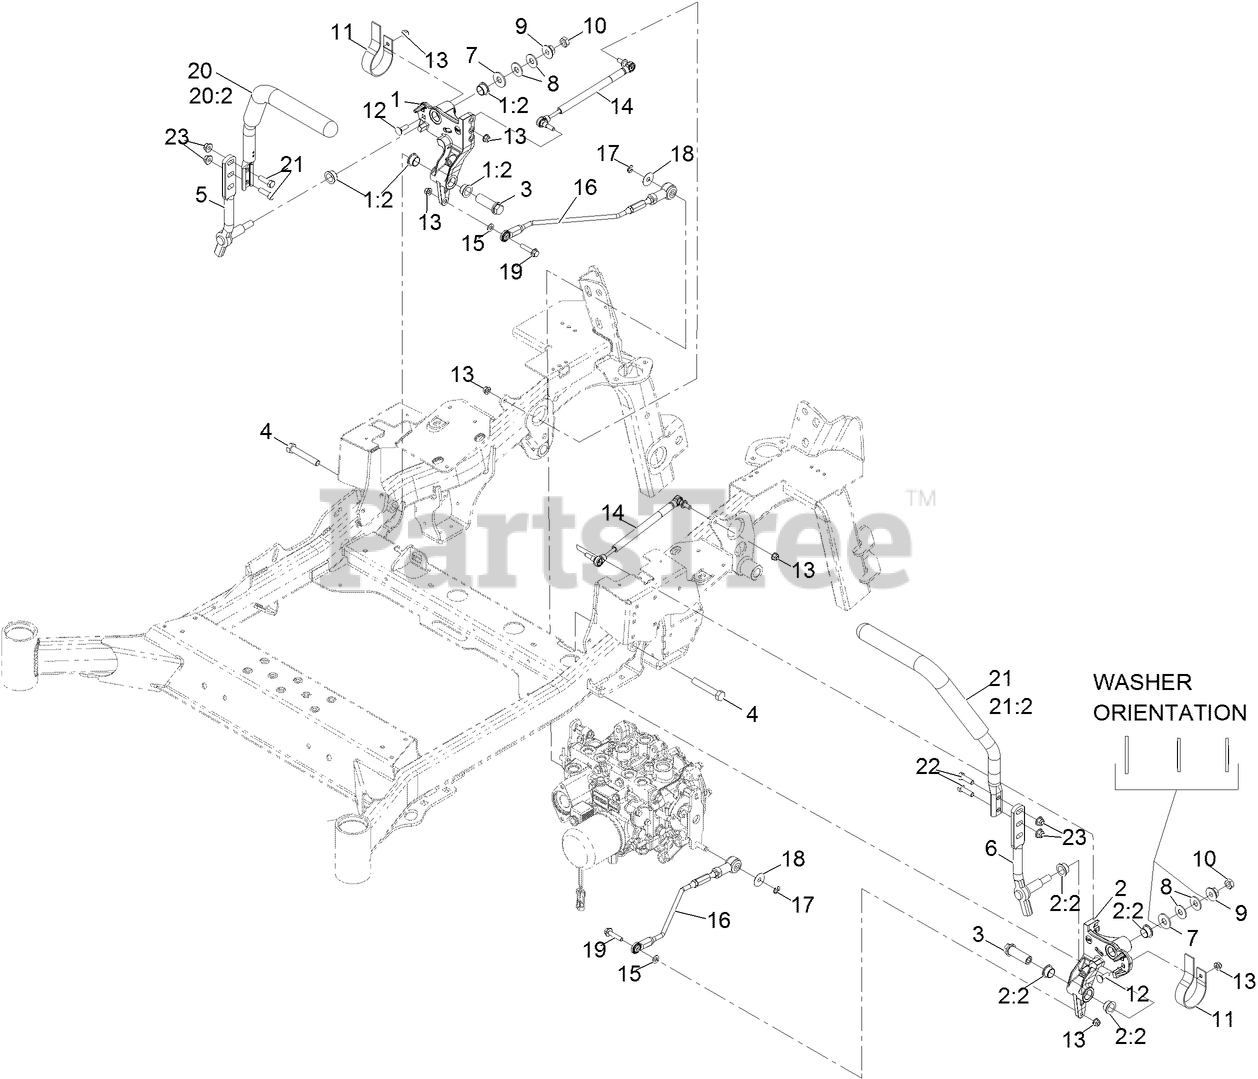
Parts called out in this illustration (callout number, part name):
1	RH MOTION CONTROL AND BUSHING ASM
1:2	BUSHING-FLANGE
2	LH MOTION CONTROL AND BUSHING ASM
2:2	BUSHING-FLANGE
3	HUB-THREADED
4	SCREW-HH
5	LEVER-CONTROL MOTION, RH
6	LEVER-CONTROL MOTION, LH
7	WASHER-FLAT
8	WASHER-SPRING
9	NUT-HF
10	NUT-JAM
11	SPRING-LEAF
12	BOLT-CARR
13	NUT-HF, NI
14	DAMPER-CONTROL, MOTION
15	WASHER-PLAIN
16	FRONT LINKAGE ROD ASM
17	RING-RETAINING
18	WASHER-PLAIN
19	SCREW-HHF
20	RH STEERING HANDLE ASM
20:2	GRIP-CONTROL, LEVER
21	LH STEERING HANDLE ASM
21:2	GRIP-CONTROL, LEVER
22	SCREW-HH
23	NUT-HF, NI
